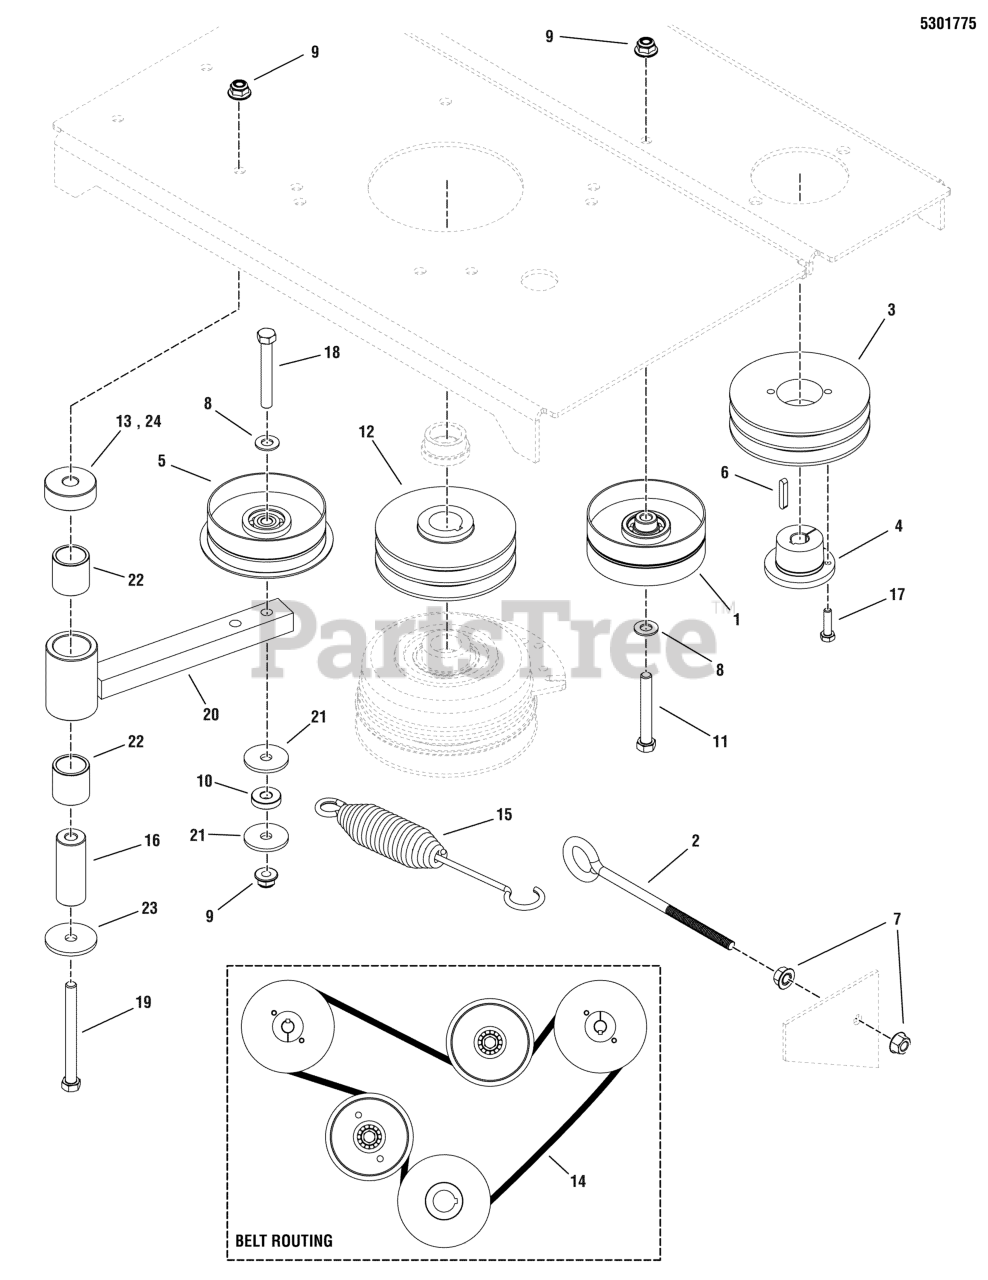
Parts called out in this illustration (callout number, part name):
1	PULLEY-IDLER, 5.00OD, .385ID, 1.50W STL
2	EYE BOLT, 3/8-16 X 8, 1 EYE
3	PULLEY, PUMP DRIVE
4	BUSHING, TAPERED HUB
5	PULLEY, IDLER, SINGLE FLANGE
6	KEY, 5MM SQ. W/ RADIUS
7	NUT, 3/8-16 HEX
8	WASHER, 3/8 SAE
9	NUT, 3/8-16 HEX NYLOCK FLANGE
10	SPACER, .39 X 1.00 X .25
11	BOLT, 3/8-16 X 2-1/4" GD5 CZ
12	PULLEY, CRANKSHAFT, 1.126 ID X 4.75 OD
13	SPACER, .51 X 1.75 X .63
14	BELT, BANDED A-SEC,64.76EL,POLY,RAW EDGE
15	SPRING, EXTENSION, SWIVEL. LONG HOOK
16	SPACER, .39 X 1.000 X 2.55, SS
17	BOLT, 1/4-20 X 1" GD5 CZ
18	BOLT, 3/8-16 X 2-3/4" GD5 CZ
19	BOLT, 3/8-16 X 4" GD5 CZ
20	See "PUMP DRIVE [Cast Idler Arm for replacing Steel Pump Drive Idler Arm]"
21	WASHER, .390 X 1.50 X .109, YZ
22	BUSHING, BRASS, 1.25X1X1.25
23	WASHER, .41 X 1.75 X .14
24	SPACER, .45 X 1.88 X .38
